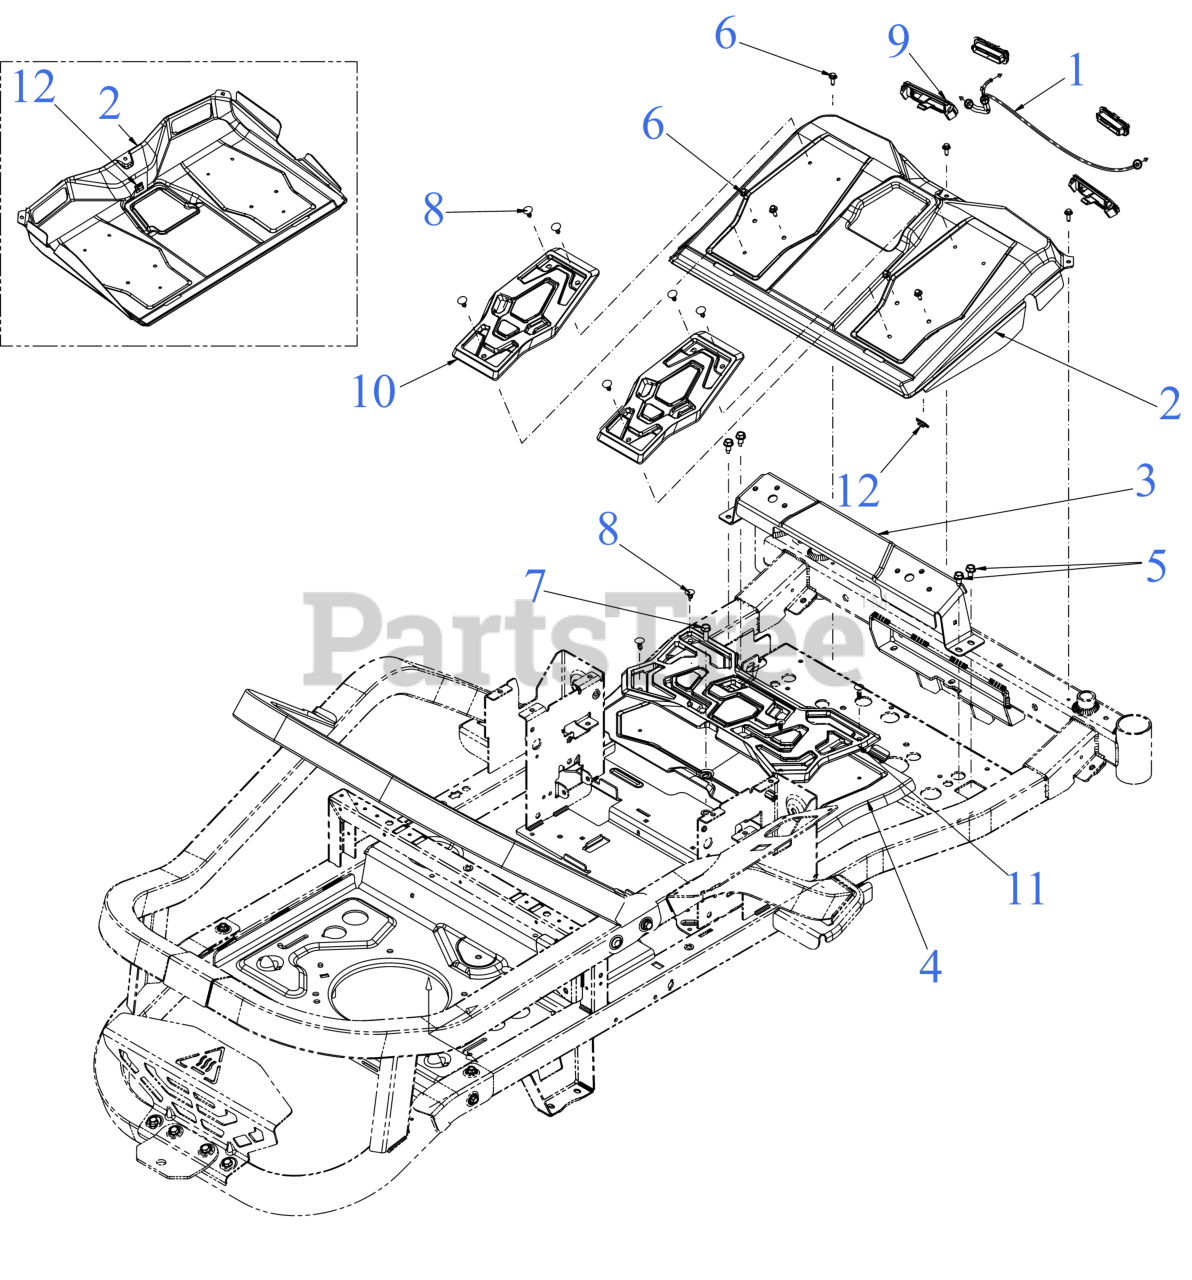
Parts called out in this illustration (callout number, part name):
1	HEADLIGHT HARNESS (W/LED)
2	FOOTREST
3	STEERING SUPPORT BRACKET
4	FLOORBOARD
5	SCREW 5/16-18 x .750
6	SCREW M6-1 x .625
7	SCREW 5/16-18 x .875 GR5
8	RATCHET CLIP .250
9	HARNESS CLIP
10	LIGHT BEZEL
11	FLOORBOARD MAT (UPPER)
12	FLOORBOARD MAT (LOWER)
